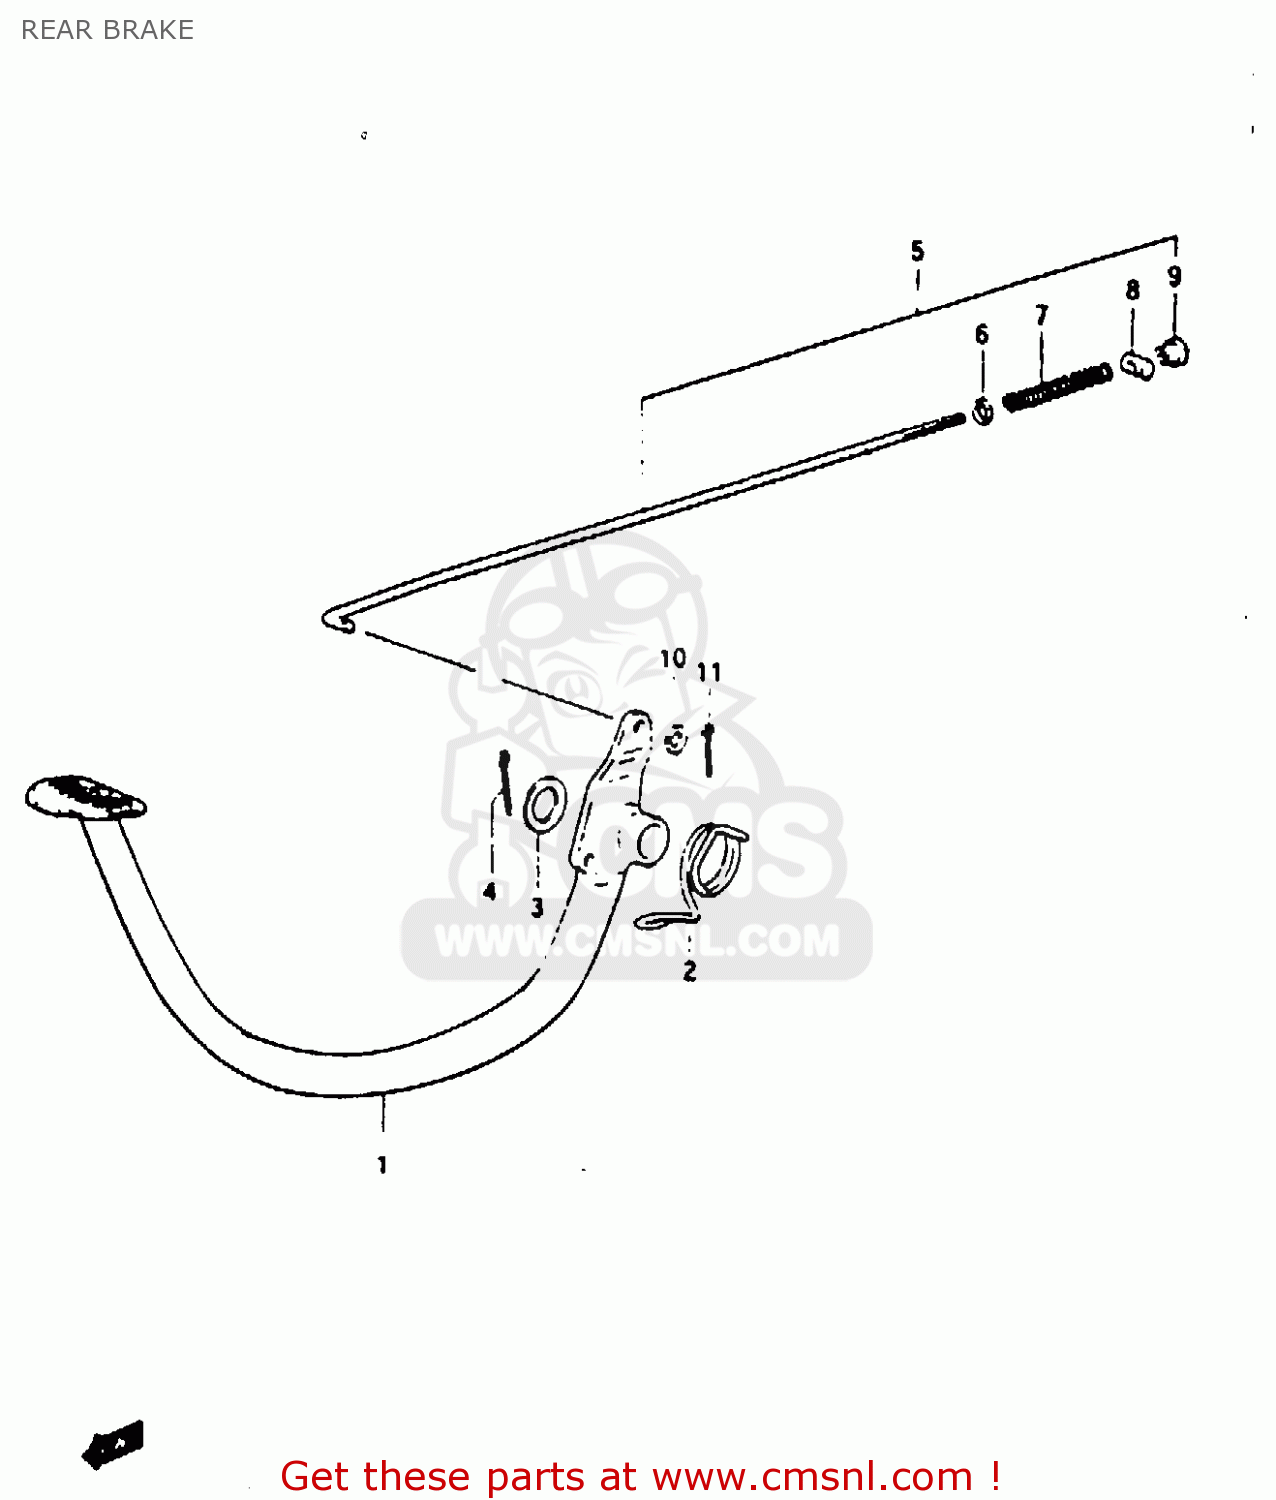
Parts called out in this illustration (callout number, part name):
1	PEDAL,BRAKE
2	SPRING
3	WASHER(15.5X26X2.3)
4	COTTER PIN
5	ROD ASSY, REAR BRAKE
6	WASHER
7	SPRING
8	PIN(11X18)
9	NUT
10	WASHER
11	PIN 20X20
